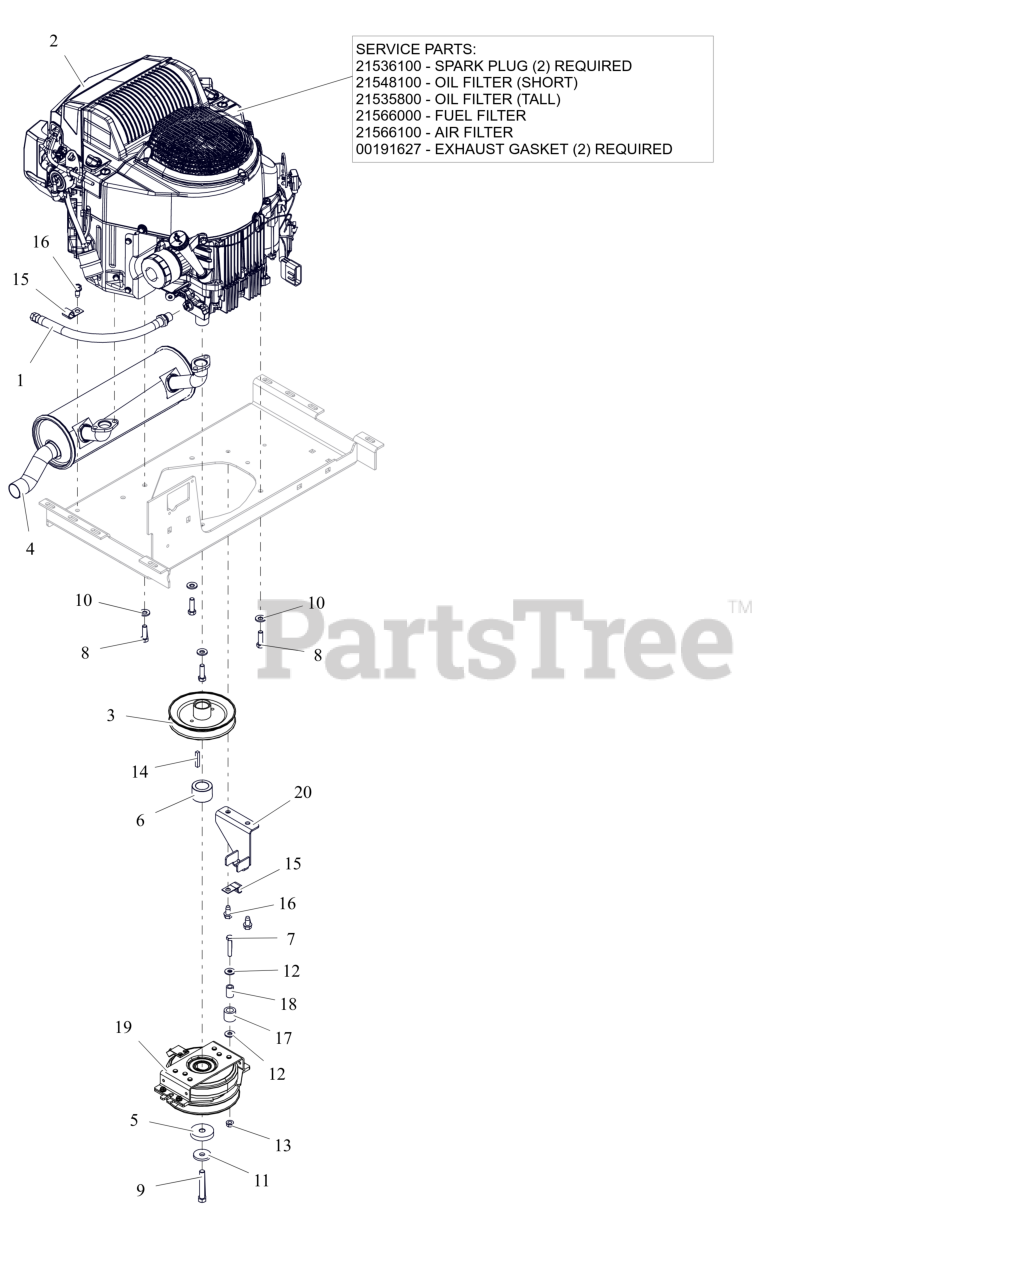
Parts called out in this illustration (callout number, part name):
1	HOSE, OIL DRAIN
2	ENGINE, KAWASAKI FT730
2	PLUG, SPARK
2	OIL FILTER, KAWASAKI FR
2	FILTER,OIL - KAW
2	FUEL FILTER, KAWASAKI
2	AIR FILTER, KAWASAKI
2	GASKET, MUFFLER S/O
3	WLDMT, TRANSAXLE DRIVE PULLEY
4	MUFFLER, KAW FX691/730
5	SPACER, .450X2.00X.396
6	SPCR, 1.125 x 1.750 x 1.147
7	BLT, HEX .31-18X1.75 G5 ZCC
8	BLT, HEX .38-16X1.25 G5 ZCC NT
9	BLT, HEX 0.4375-20X2.75 G8 ZCC NT
10	WASHER, 3/8" SPRING DISC
11	WASHER, 7/16" SPRING DISK
12	WSHR,FLT .375X.875X.083 ZCC
13	NUT,LK-CTR-FLG .31-18 GF ZCC
14	KEY-SQ .25 X 1.50 X .25 SAE
16	SCR,TAP .375-16X.75 HWH TR ZCC
17	BUMPER,RUBBER .62X1.0X.88 LG
18	BUSH.,S.391X.622X.950 ST
19	CLUTCH- OGURA GT2.75-DC03(D)
20	BRKT- CLUTCH STOP - BLACK
